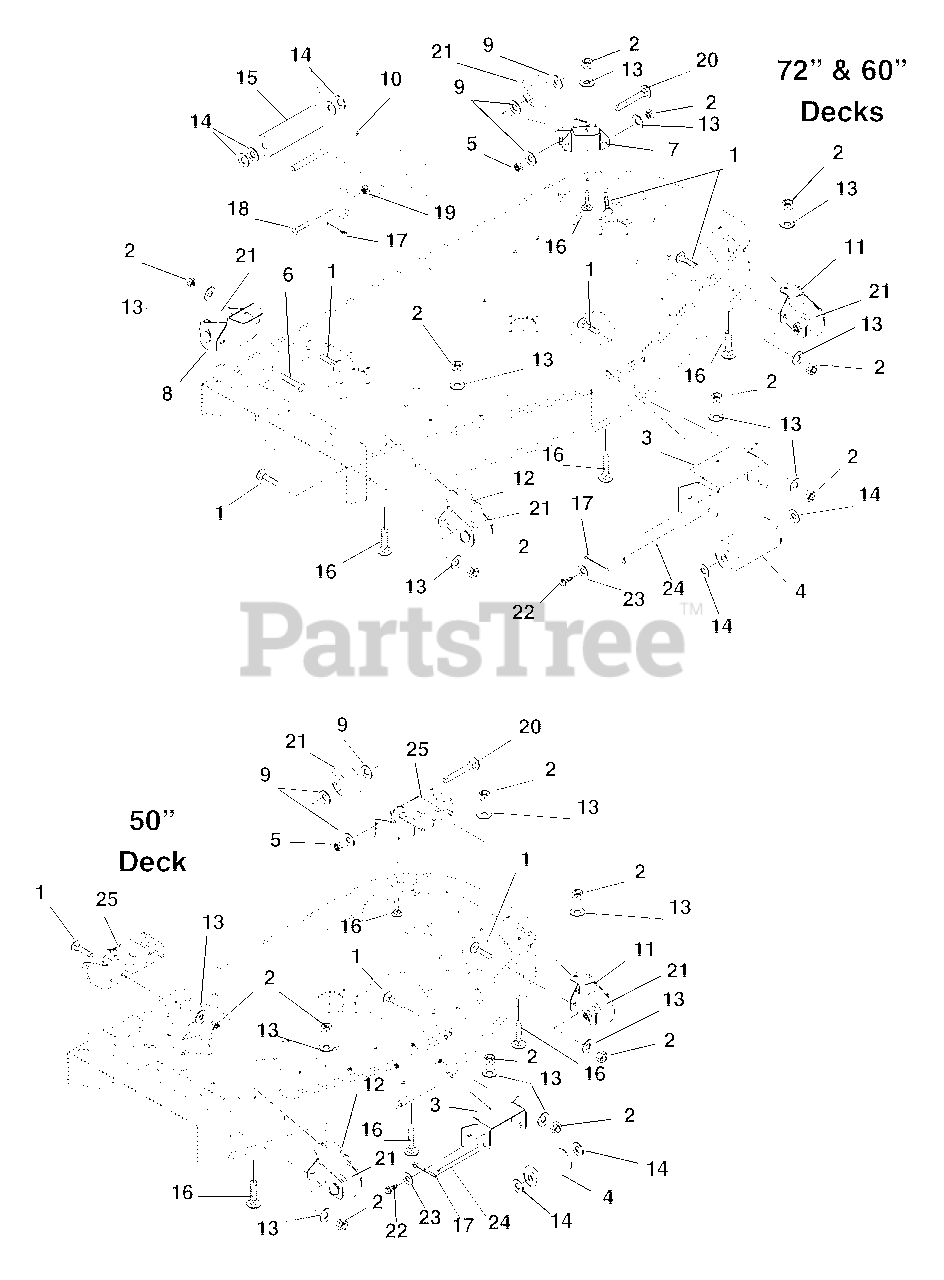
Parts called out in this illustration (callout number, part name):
1	Bolt-Round Head Square Neck .38-16 x 1.00 Grade 5 (72" & 60" Deck)
1	Bolt-Round Head Square Neck .38-16 x 1.00 Grade 5 (50" Deck)
2	Nut-Locking-Nylon .38-16 (72" & 60" Deck)
2	Nut-Locking-Nylon .38-16 (50" Deck)
3	Bracket, Anti-Scalp Roller
5	Nut-Locking-Nylon .50-13 (72" & 60" Deck)
5	Nut-Locking-Nylon .50-13 (50" Deck)
6	Bolt-Hex .38-16 x 1.00 Grade 5 (60" Deck)
7	Weldment-Wheel Support Left Hand (72" & 60" Deck)
8	Weldment-Wheel Support Right Hand (72" & 60" Deck)
9	Washer-Flat-Steel .531 x 1.06 x .095 (72" & 60" Deck)
9	Washer-Flat-Steel .531 x 1.06 x .095 (50" Deck)
10	Shaft, Center Roller (60" Deck)
11	Weldment-Left Front Roller Bracket (72" & 60" Deck)
11	Weldment-Wheel Support Left Hand (50" Deck)
12	Weldment-Right Front Roller Bracket (72" & 60" Deck)
12	Weldment-Wheel Support Right Hand (50" Deck)
13	Washer-Flat-Steel .406 x .812 x .065 (72" & 60" Deck)
13	Washer-Flat-Steel .406 x .812 x .065 (50" Decks)
14	Washer-Flat-Steel .656 x 1.31 x .095 (72" & 60" Deck)
14	Washer-Flat-Steel .656 x 1.31 x .095 (50" Deck)
15	Roller, Gage (60" Deck)
16	Bolt-Round Head Square Neck .38-16 x 1.25 Grade 5 (72" & 60" Deck)
16	Bolt-Round Head Square Neck .38-16 x 1.25 Grade 5 (50" Deck)
17	Pin-Cotter .25 x 2.00 (72" & 60" Deck)
17	Pin-Cotter .25 x 2.00 (50" Deck)
18	Bolt-Hex .25-20 x .75 Grade 5 (72" & 60" Deck)
19	Nut-Locking-Center .25-20 (72" & 60" Deck)
20	Bolt-Round Head Square Neck .50-13 x 5.00 Grade 2 (72" & 60" Deck)
20	Bolt-Round Head Square Neck .50-13 x 5.00 Grade 2 (50" Deck)
21	Wheel, 3 x 5
22	Screw-Self Tapping .25-20 x .50 x Hex Washer Head
23	Washer-Flat-Steel .281 x .62 x .065
25	Bracket, Rear Anti Scalp Roller (50" Deck)
